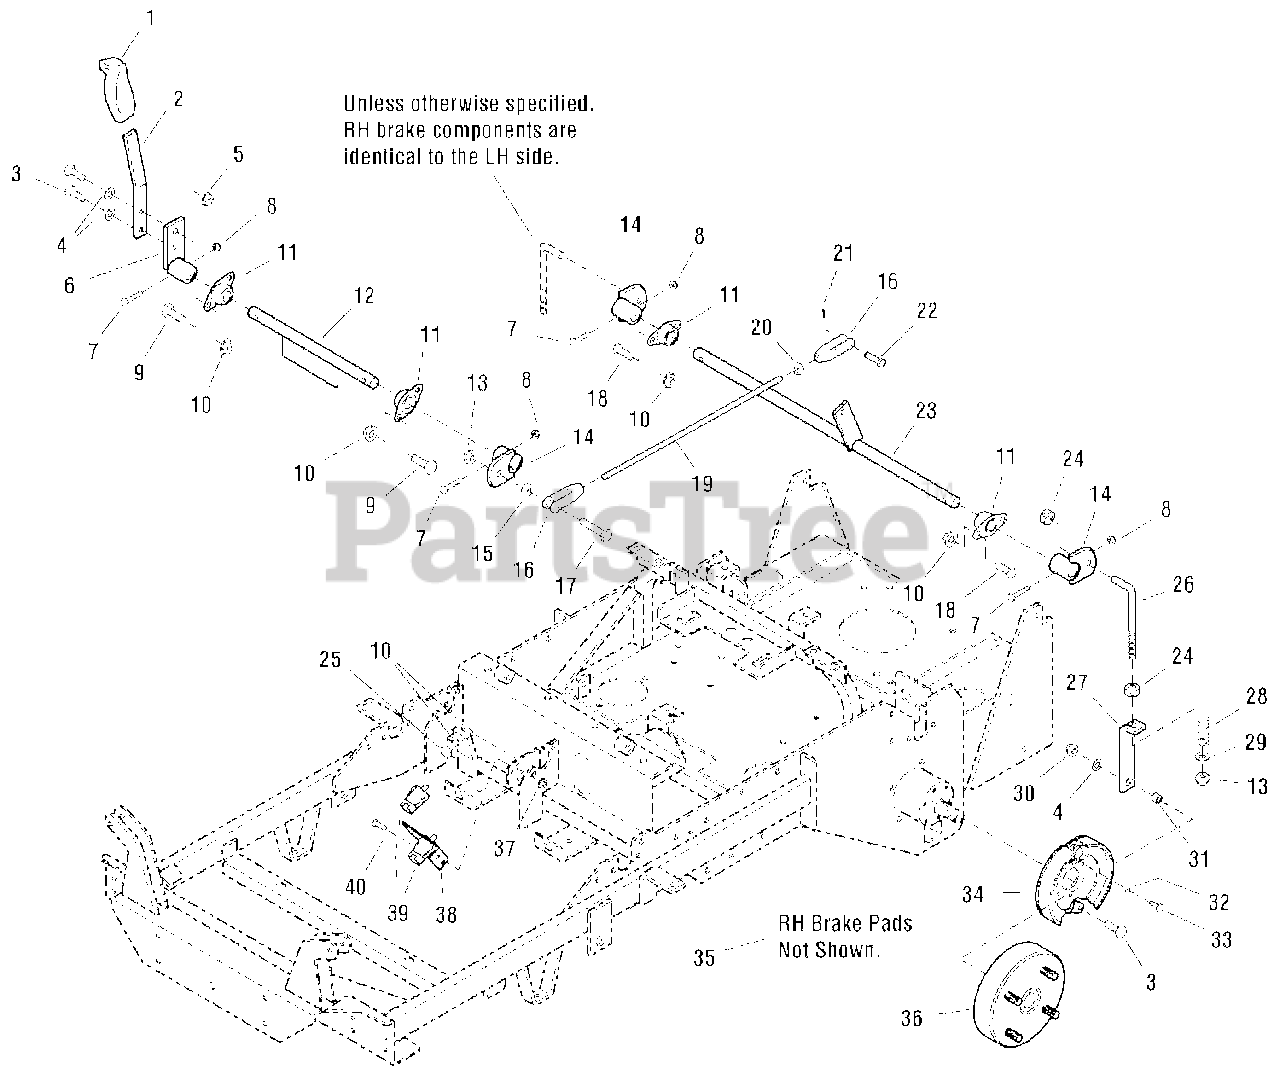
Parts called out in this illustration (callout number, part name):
1	GRIP
2	BRAKE HANDLE
3	CAPSCREW, HEX HEAD, 5/16-18 X 1
4	WASHER, FLAT, 5/16
5	NUT, HEX SERRATED FLANGE, 5/16-18
6	MOUNT, BRAKE HANDLE
7	CAPSCREW, HEX HEAD, 1/4-20 X 1-3/4
8	NUT, HEX NYLON LOCK, 1/4-20
9	BOLT, 3/8-16 X 3/4" GD5 CZ
10	NUT, HEX SERRATED FLANGE, 3/8-16
11	BEARING, FLANGE
12	BRAKE SHAFT, FRONT
13	NUT, HEX NYLON LOCK, 3/8-16
14	BRAKE LINKAGE PIVOT
15	NUT, HEX, 3/8-16
16	CLEVIS, 3/8-24
17	BOLT, 3/8-16 X 2, GD5, CZ
18	CAPSCREW, BUTTON ALLEN HEAD, 3/8-16 X 3/4
19	ROD
20	NUT, HEX, 3/8-24
21	PIN, COTTER
22	PIN, CLEVIS, 3/8 X 1
23	BRAKE SHAFT, REAR
24	COLLAR, SET, 3/8
25	CAPSCREW, HEX HEAD, TFL, 3/8-16 X 1-3/4
26	ROD, BRAKE ADJSUTMENT
27	BRAKE LINK
28	SPRING, COMPRESSION
29	WASHER, FLAT, 3/8
30	NUT, HEX NYLON LOCK, 5/16-18
31	PIVOT SLEEVE
32	WASHER, LOCK, 1/4
33	CAPSCREW, HEX HEAD, M6 X 14MM
34	BRAKE ASSEMBLY, LH
36	BRAKE DRUM, 4 BOLT
37	NUT, HEX SERRATED FLANGE, 1/4-20
38	SWITCH MOUNT BRACKET
39	SWITCH, PLUNGER, SNAP IN
40	CAPSCREW, HEX HEAD, 1/4-20 X 5/8
